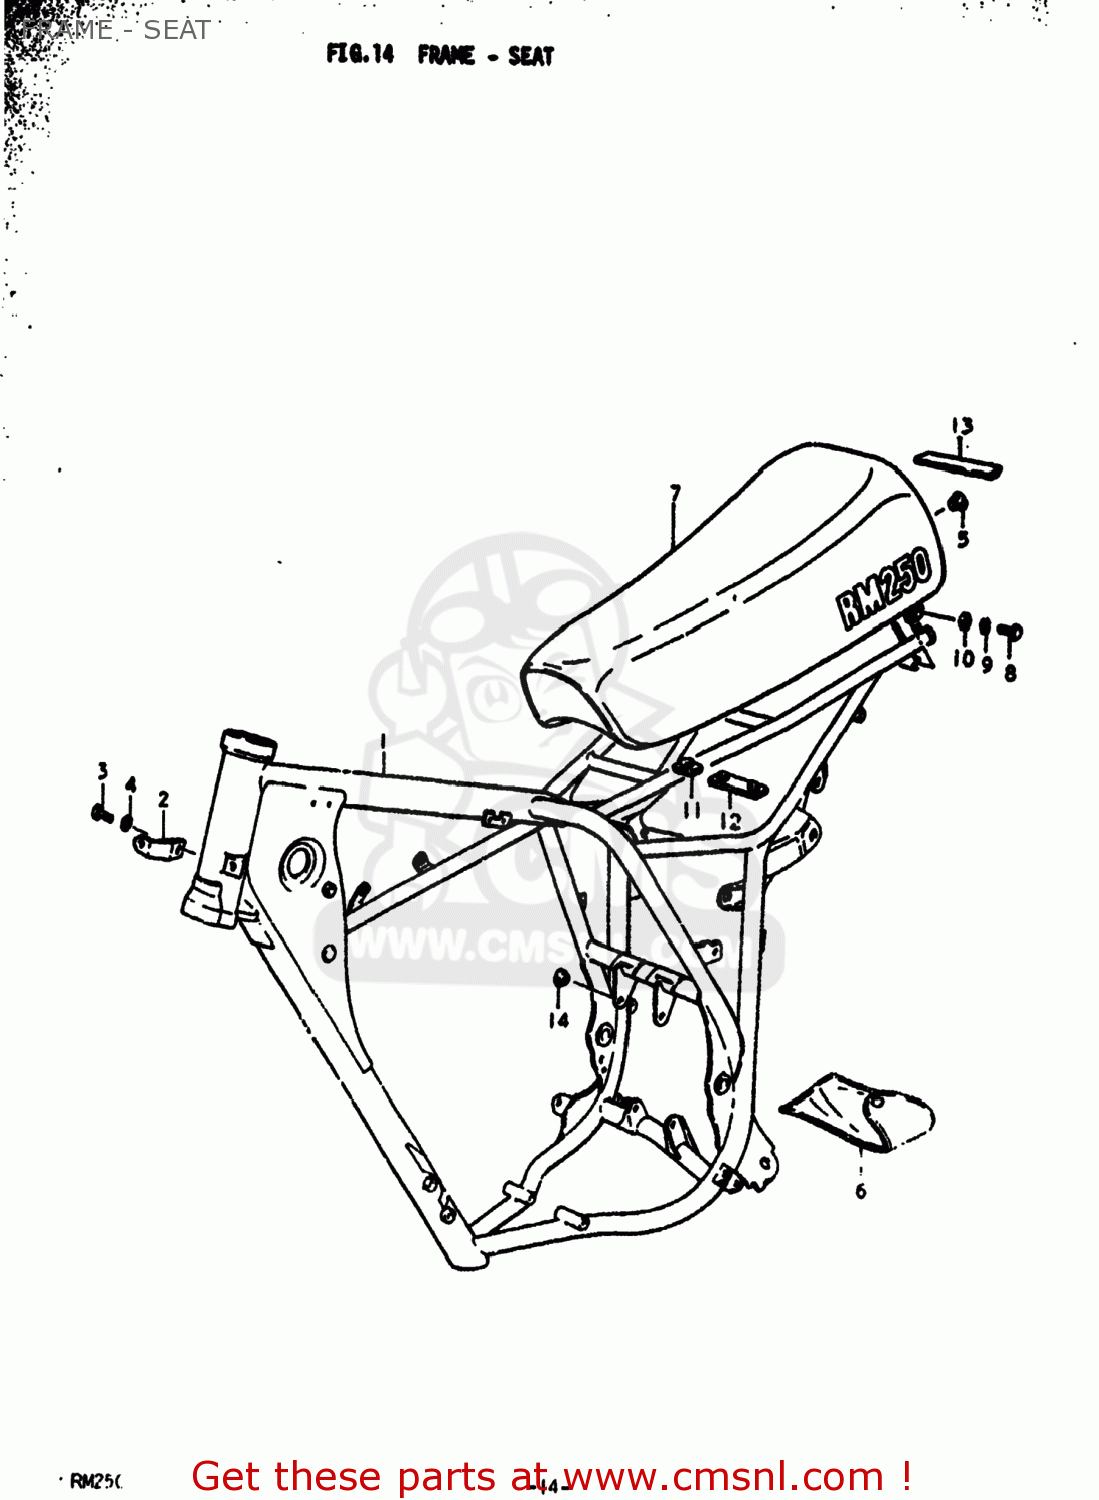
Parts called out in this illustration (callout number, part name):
1	FRAME
2	PLATE,ENGINE MOUNTING
3	BOLT
4	LOCK WASHER
5	CAP(OD:17)
6	TOOL SET
7	SEAT ASSEMBLY
8	BOLT
9	LOCK WASHER
10	WASHER
11	CUSHION
12	CUSHION
13	CUSHION,FRAME
14	PLATE,FRAME BODY
